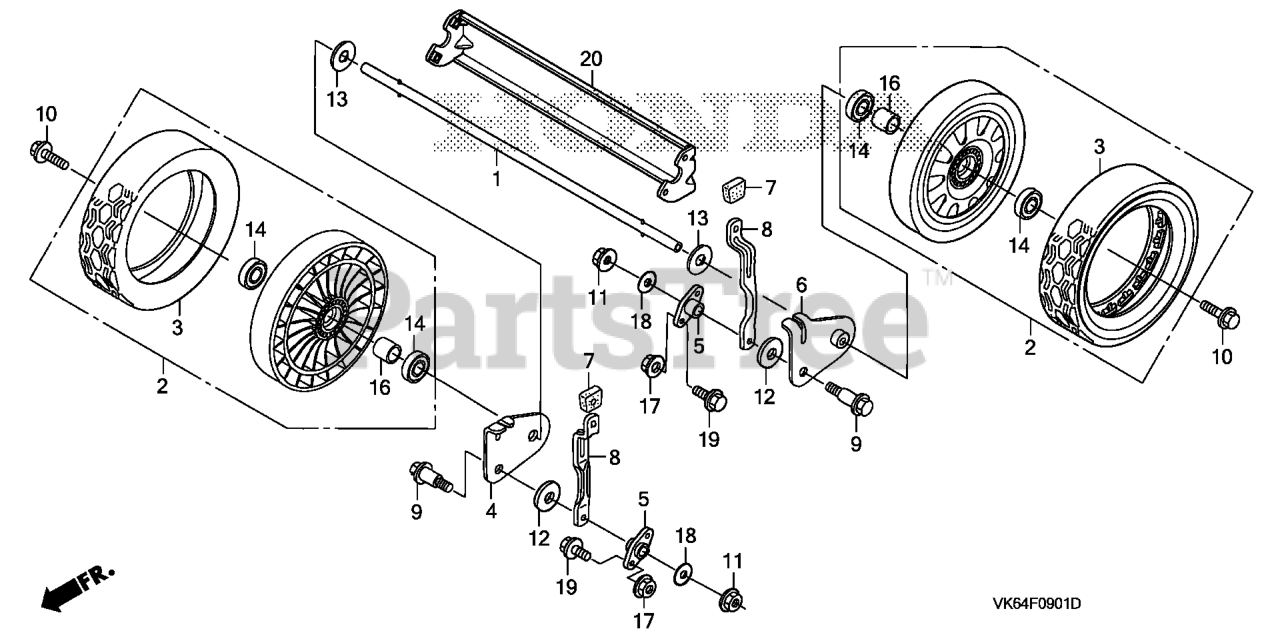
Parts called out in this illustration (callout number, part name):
1	SHAFT, RR. AXLE
2	WHEEL ASSY., RR. *NH462R* (VINTAGE GRAY SOLID)
3	TIRE (9 INCH)
4	ARM, R. RR. ADJUSTING
5	HOLDER, RR. AXLE
6	ARM, L. RR. ADJUSTING
7	GRIP, ADJUSTER
7	GRIP, ADJUSTER *NH105* (MAT BLACK)
8	PLATE, RR. ADJUSTER
9	BOLT, RR. HEIGHT ADJUSTER
10	BOLT, WHEEL
11	NUT, SELF-LOCK (8MM)
11	NUT, FLANGE (8MM)
12	WASHER, WHEEL SPACER (12.7X28.5X3.2)
13	WASHER, WHEEL SPACER (12.7X28.5X3.2)
14	BEARING, RADIAL BALL (6201)
16	COLLAR, WHEEL
17	NUT, FLANGE (6MM)
18	WASHER, PLAIN (8MM)
19	BOLT, FLANGE (6X12) Use up to Engine SN 1543277.
20	PLATE, RR. AXLE
